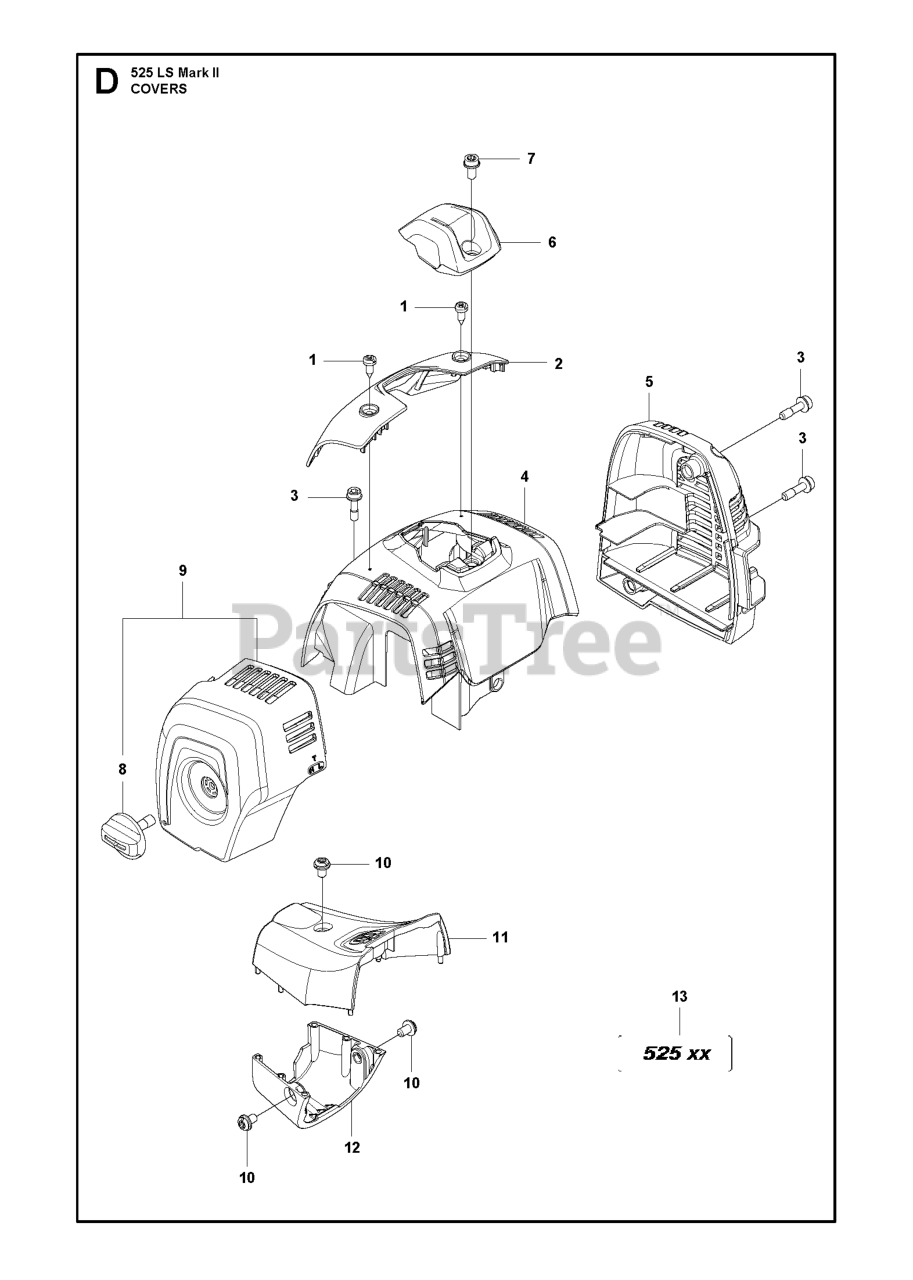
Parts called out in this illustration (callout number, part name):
2	ARM PROTECTION
3	BOLT
4	CYLINDER COVER
5	MUFFLER GUARD HVA GZ26S
7	SCREW HEXALOBULAR SOCKET HEAD
9	FILTER COVER ASSY
12	COVER CLUTCH HOUSING LOWER
13	DECAL
